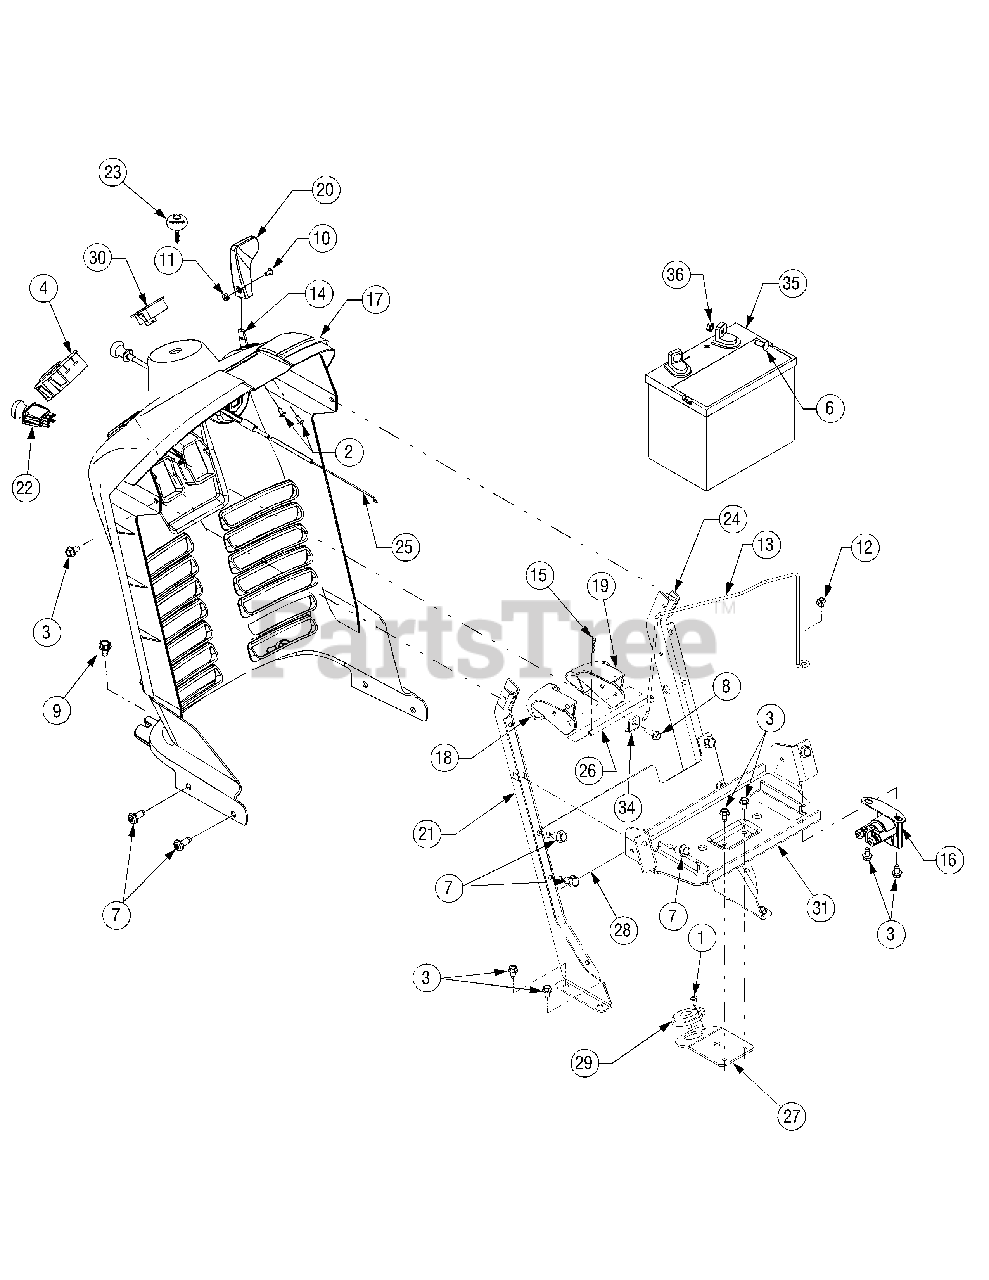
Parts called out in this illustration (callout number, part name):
1	Screw, #10-16 x .5
2	Screw, #10-24 x .375
3	Screw, Self-tapping, 1/4-20, 0.500
4	Switch Module, Ignition
6	Screw, Flange, 1/4-20, .75,
7	Screw, Hex, 5/16-12 x .75
8	Screw, 1/4-15, 0.750
9	Screw, Torx Hd. Tapp. 5/16-18 x .75
10	Screw, Machine, #8-32, 0.375, Trus Phillips
11	Nut, 8-32
12	Nut, Nylon Lock, 1/4-20
14	Control, Throttle, 27.4 (LT1042 & LT1045)
14	Control, Throttle, 38.0 (LT1046 & LT1050)
15	Internal Cotter Pin, .072 x 1.13
16	Solenoid, 12V, 100 Amp
17	Dash
18	Lever, Dash, Cruise
19	Lever, Dash, Brake
20	Knob, Throttle Control
23	Ignition Key, Plastic
23	Ignition Key, Metal
25	Control, Choke, 24.0 (LT1042 & LT1045)
25	Control, Choke, 37.5 (LT1046 & LT1050)
26	Rod, .250 Dia x 4.25 Lg.
30	Monitor, Systems Indicator / Hour Meter
35	Battery, 190 CCA (LT1042 & LT1045)
35	Battery, 235 CCA (LT1046 & LT1050)
36	Nut, Sems, 1/4-20
